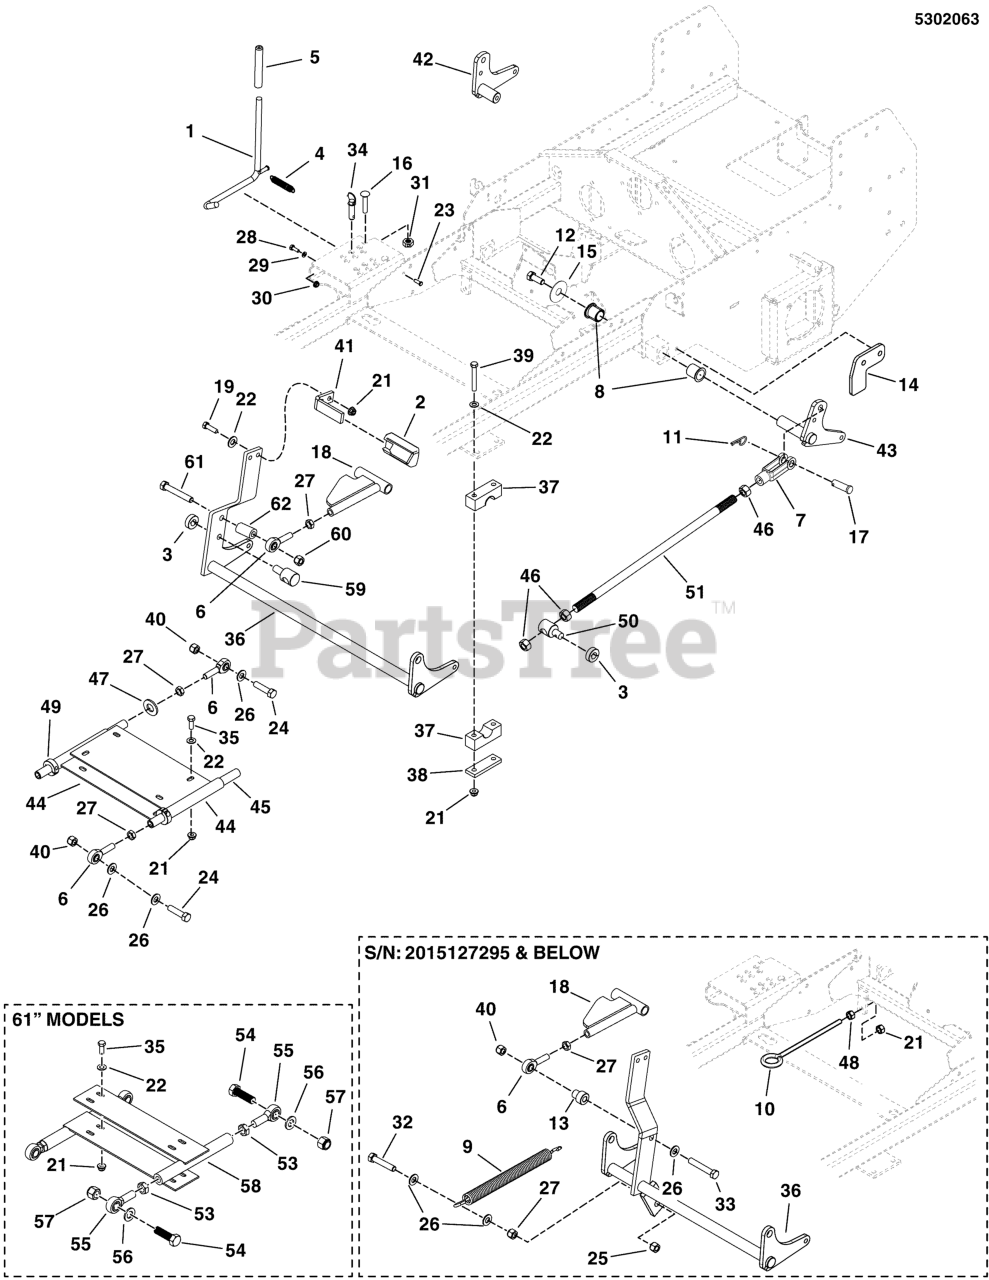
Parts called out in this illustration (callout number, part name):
1	WELD, ROD DECK LIFT - BLK
2	PEDAL, Rubber
3	COLLAR, 5/8 SPLIT
4	SPRING, EXTENSION
5	GRIP, FOAM
6	BALL JOINT, 1/2-20, MALE
7	CLEVIS, 1/2-20, STEEL
8	BUSHING, 1.00 X 1.13 X 1.38, PLASTIC
9	SPRING, DECK LIFT ASSIST
10	EYE BOLT, 3/8-16 X 8, 1 EYE
11	PIN, HAIR, .0915 X 1-7/8
12	BOLT, 3/8-16 X 3/4, GD5, YZ WITH PATCH
13	SPACER, .53 X 1.00 X 1.00
14	PLATE, DECK STOP - RED
15	WASHER, .390 X 1.50 X .109, YZ
16	BOLT, 3/8-16 X 2, CARRIAGE
17	PIN, CLEVIS, 1/2 X 1 1/2, YZP
18	WELD, DECK ADJUST LINK - RED
19	BOLT, 3/8-16 X 1-1/4" GD5 CZ
20	BOLT, 1/2-13 X 2-3/4 GD5 CZ
21	NUT, 3/8-16 HEX NYLOCK FLANGE
22	WASHER, 3/8 SAE
23	PIN, CLEVIS, 1/4 X 7/8, PLATED
24	BOLT, 1/2-20 X 1-3/4" GD8 CZ
25	NUT, Hex, Nylon Lock, 1/2-20
26	WASHER, 1/2 GD9 YZ
27	NUT, 1/2-20 HEX JAM
28	BOLT, 1/4-20 X 3/4 GD5 YZ
29	WASHER, 1/4 SAE
30	NUT, 1/4-20 HEX SERR. FLANGE
31	NUT, 3/8-16 HEX SIDE LOCK
32	BOLT, 1/2-20 X 2-1/4 GD5 CZ
33	BOLT, 1/2-13 X 3" GD5 CZ
34	PIN, HITCH, 1/2 X 2.00 OAL, YP
35	BOLT, 3/8-16 X 1" GD5 CZ
37	PIVOT BLOCK, PLASTIC
38	PLATE, PIVOT BLOCK SUPPORT - BLK
39	BOLT, 3/8-16 X 2-3/4" GD5 CZ
40	NUT, Hex, Nylon Lock, 1/2-20
41	PEDAL, DECK LIFT, IS2500Z - BLK
42	WELD, PIVOT, DECK LIFT, RH - RED
43	WELD, PIVOT, DECK LIFT, LH - RED
44	WELD, DECK STABILIZER - BLK
46	NUT, 5/8-11 HEX
47	WASHER, 1/2 SAE
48	NUT, 3/8-16 HEX SERRATED FLANGE
49	COLLAR, 3/4 SPLIT
50	PIVOT, SPRING ROD
52	SPACER, .52 X 1.00 X 1.75
53	NUT, 3/4-16 HEX JAM
54	BOLT, 3/4-16 X 2-1/2 YZ GD5
55	BALL JOINT, 3/4-16, MALE
56	WASHER, 3/4 SAE
57	NUT, 3/4-16 HEX NYLON LOCK
59	PIVOT, SPRING ROD
60	NUT, 1/2-13 HEX SIDE LOCK
61	BOLT, 1/2-13 X 4-1/2 GD5
62	SPACER, .50 X 1.00 X 2.25
